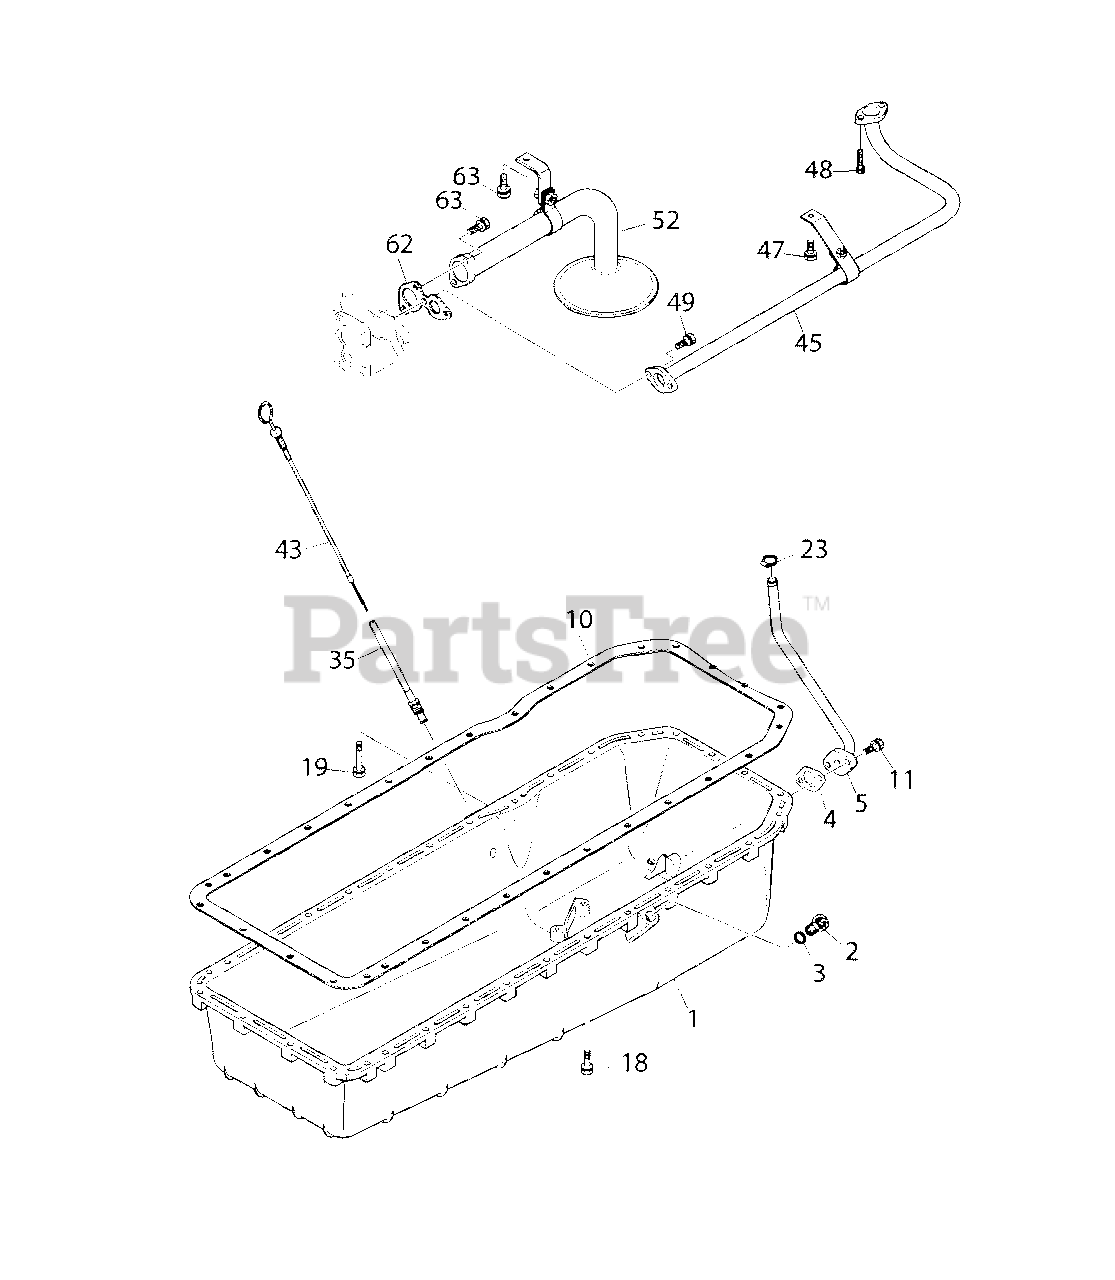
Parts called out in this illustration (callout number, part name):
1	* PAN, OIL
2	PLUG, SCREW
3	SEAL, RING
4	GASKET, OIL PIPE
5	* PIPE, OIL
10	* GASKET, OIL PAN
11	* BOLT
18	* BOLT
19	* BOLT
23	* CLAMP, HOSE
35	* TUBE, DIPSTICK
43	* DIPSTICK
45	* PIPE, OIL
47	* BOLT
48	* BOLT
49	* BOLT, HEX
52	* PIPE, OIL
62	* GASKET
63	* BOLT, HEX
